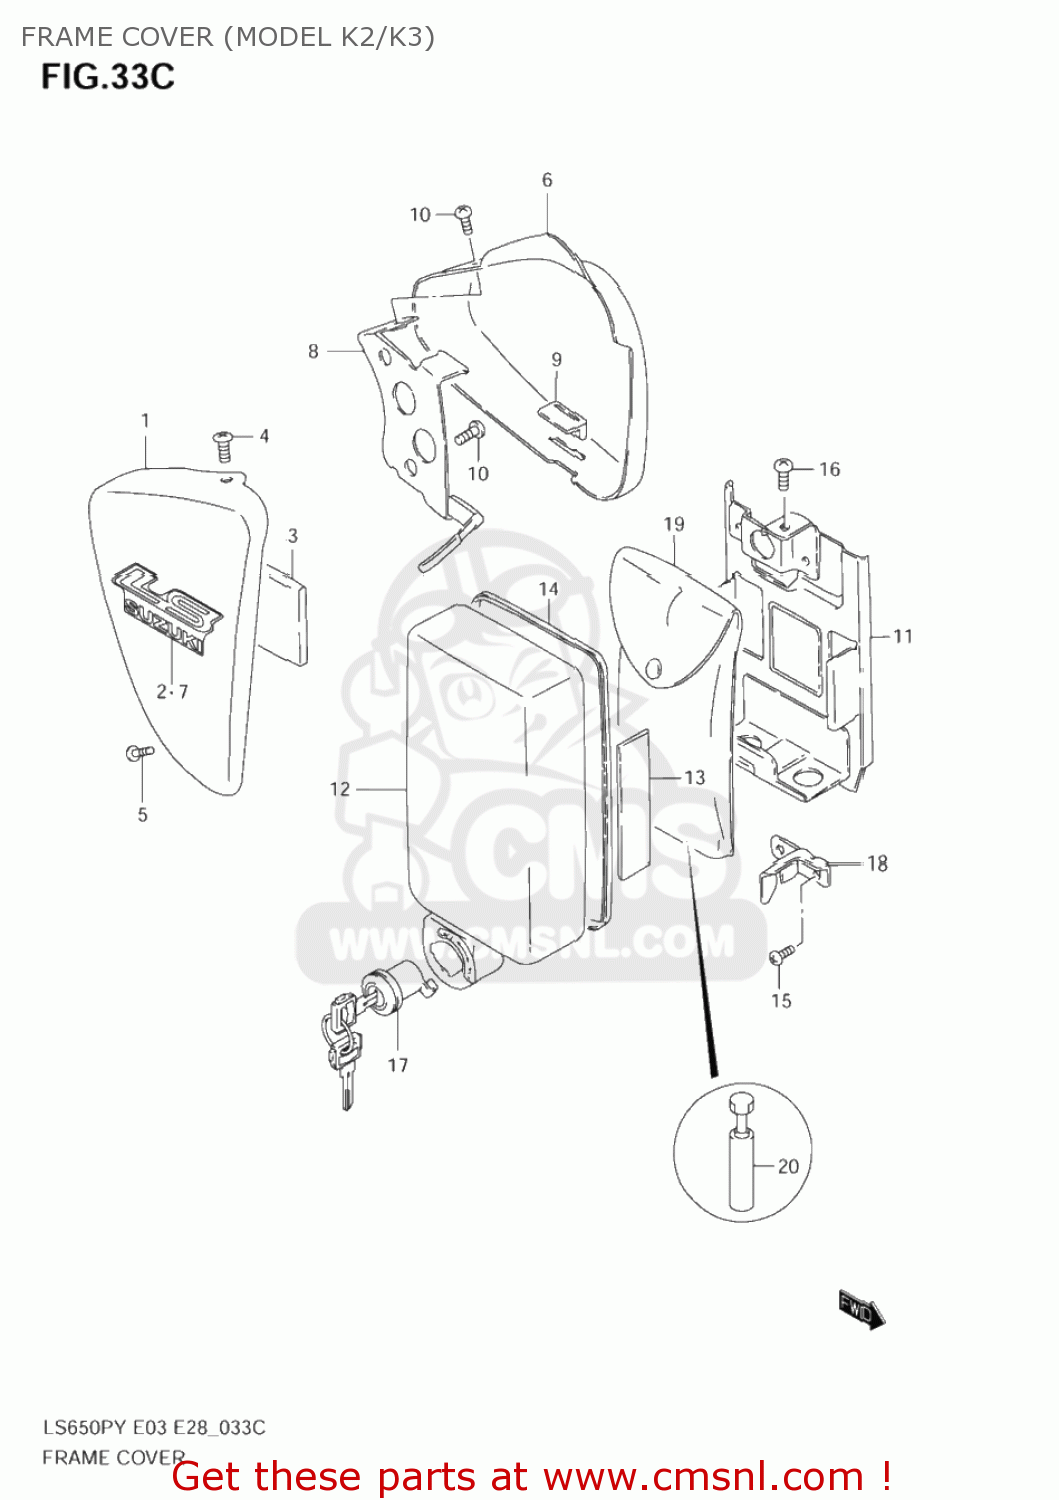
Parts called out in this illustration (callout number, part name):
1	COVER, FRAME RH (BLACK)
2	EMBLEM,FRAME COVER
3	PAD
4	SCREW
5	SCREW
6	COVER ASSY,FRAME,L(BLACK)
7	EMBLEM,FRAME COVER
8	BRACKET,FRAME COVER,L
9	CUSHION,FRAME COVER
10	SCREW
11	HOLDER,TOOL
12	COVER COMP,TOOL HOLDER
13	PROTECTOR(80X80X2)
14	MOLDING
15	SCREW
16	SCREW
17	LOCK SET,TOOL HOLDER
18	PLATE,TOOL HOLDER LOCK
19	TOOL ASSY
20	GAUGE ASSY,TENSION
